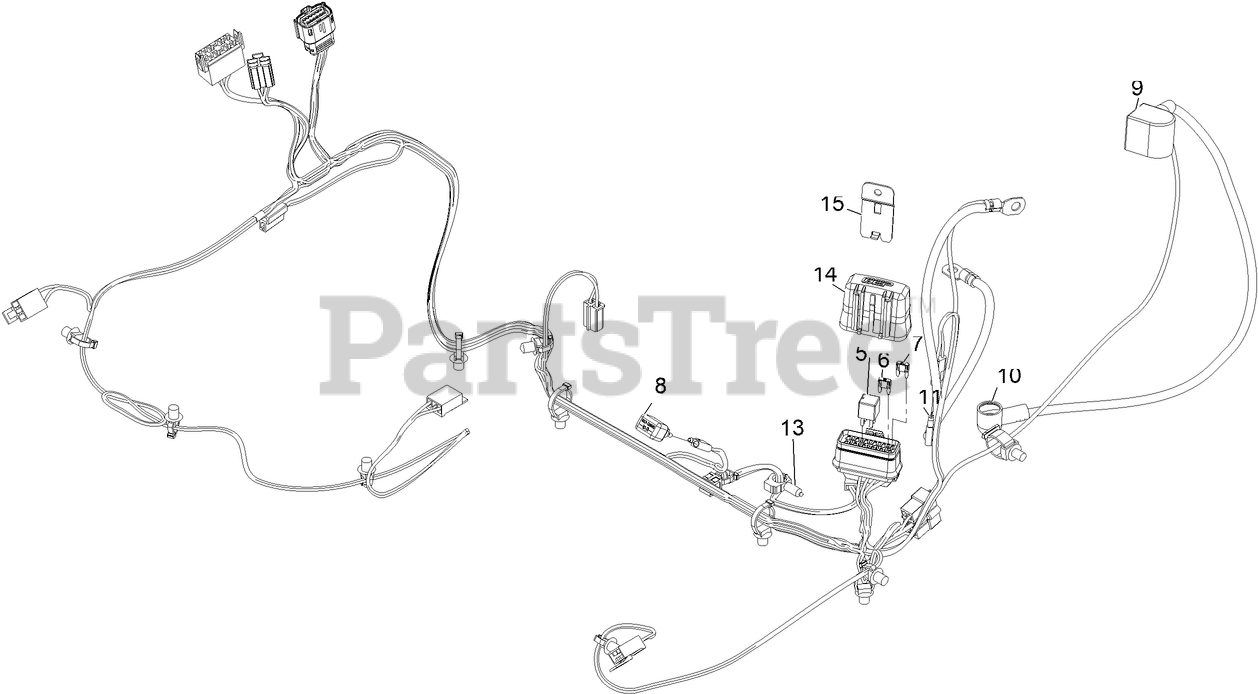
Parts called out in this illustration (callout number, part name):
5	RELAY-MICRO
6	FUSE-MINI BLADE, 15 AMP
7	FUSE-MINI BLADE, 20 AMP
9	INSULATOR-BATTERY
10	INSULATOR-SOLENOID
11	CAP-PLUG
13	CLIP-HARNESS
14	COVER-BLOCK, FUSE
15	CLIP-MOUNTING
